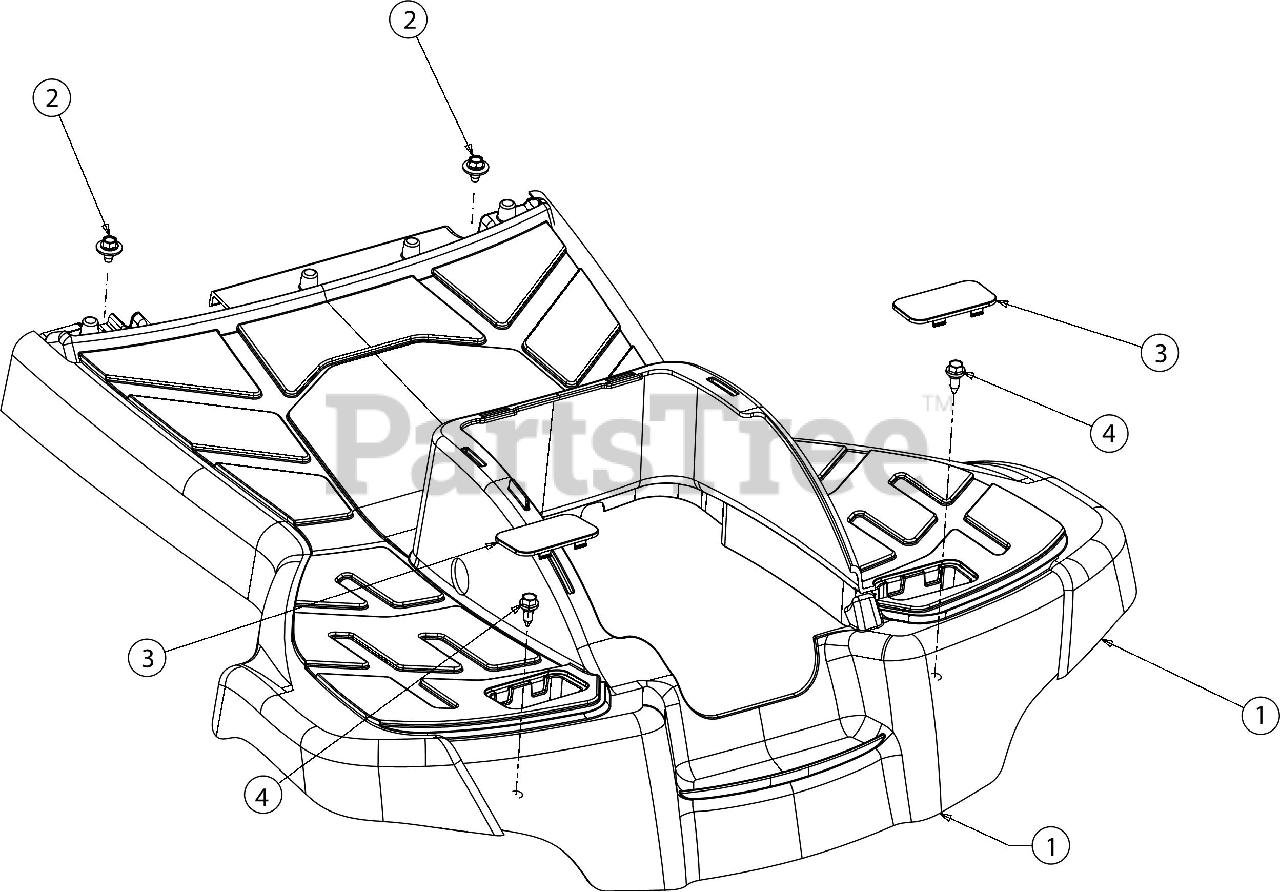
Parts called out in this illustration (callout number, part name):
1	RUNNINGBOARD W/RMC
2	SCREW 1/4-20 x .50
3	RUNNING BOARD PLUG
4	SHOULDER SCREW
